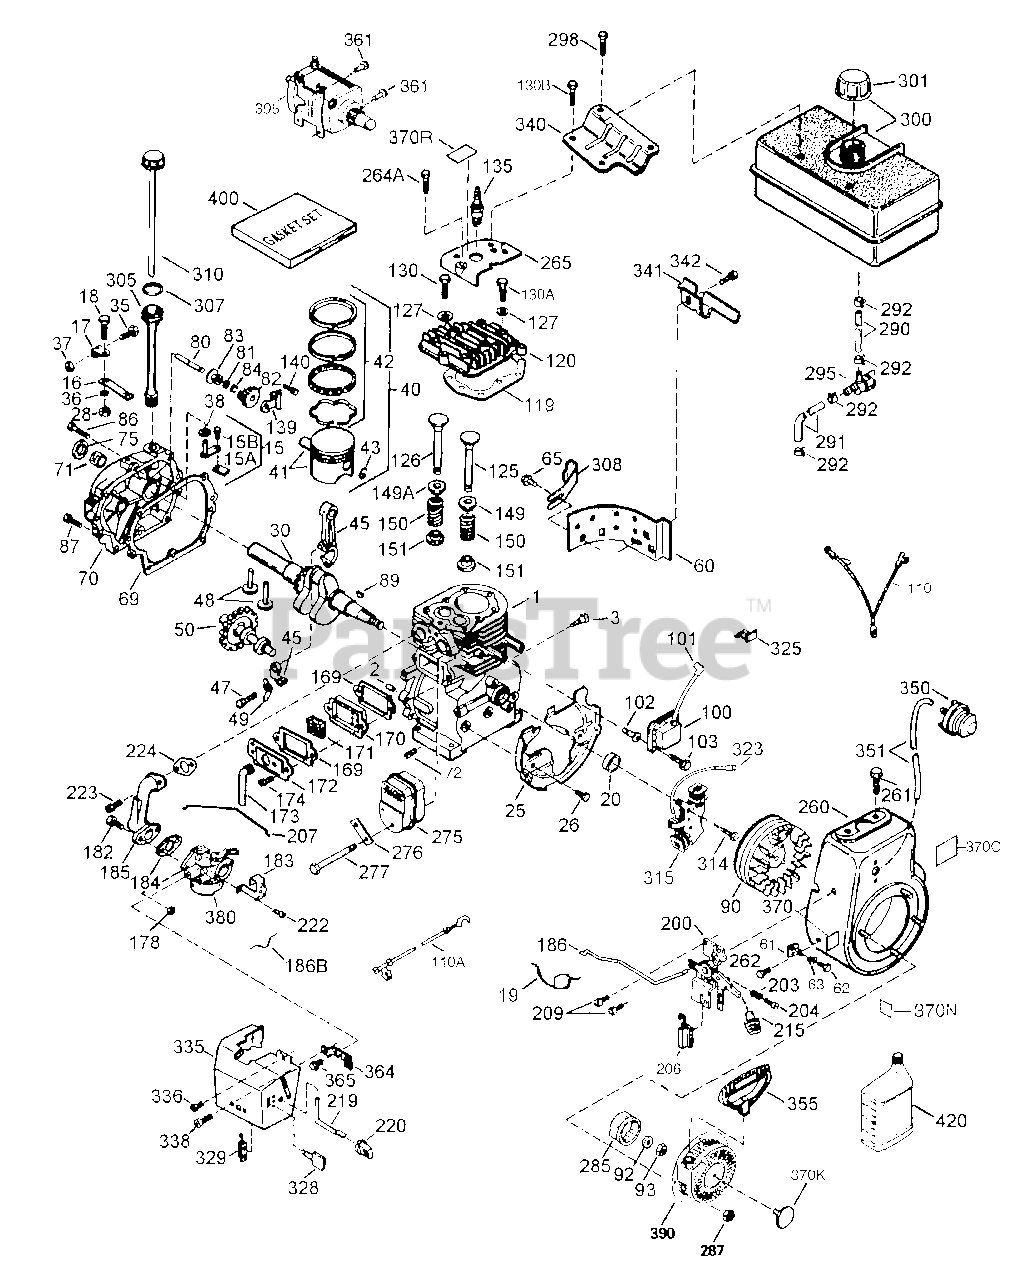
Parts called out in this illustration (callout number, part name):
1	Cylinder Asm (Incl. Ref. #2, 20, &72)
2	Dowel Pin
3	Screw
15	Governor (Incl. Ref. #15A &15B)
15A	Governor Yoke
15B	Screw
16	Governor Lever
17	Governor Lever Clamp
18	Screw
19	Spring-SpeedControl
20	Oil Seal
25	Blower Housing Baffle
26	Screw
28	Lock Nut
30	Crankshaft
35	Screw
36	Lock Washer
37	Lock Nut
38	Retaining Ring
40	Piston, Pin & Ring Set(Std.)
40	Piston, Pin & Ring Set (.010" OS)
41	Piston & Pin Asm(Std.)(Incl. Ref. #43)
41	Piston & Pin Asm(.010" OS)(Incl. Ref. #43)
42	Ring Set (Std.)
42	Ring Set (.010" OS)
43	Piston Pin RetainingRing
45	Connecting Rod Asm (Incl. Ref. #47, & 49)
47	Connecting Rod Bolt
48	Valve Lifter
49	Oil Dipper
50	Camshaft (MCR)
60	Blower HousingExtension
61	Grommet MountingBracket
62	Screw
63	Grommet
65	Screw
69	Cylinder Cover Gasket
70	Cylinder Cover (Incl. Ref. #71, 75, &80)
71	Crankshaft Bushing
72	Oil Drain Plug
75	Oil Seal
80	Governor shaft
81	Washer
82	Governor Gear Asm (Incl. Ref. #81)
83	Governor Spool
84	Retaining Ring
86	Screw
87	Screw
89	Flywheel Key
90	Flywheel (W/RingGear)
92	Lock Washer
93	Flywheel Nut
100	Solid State Ignition
101	Spark Plug Cover
102	Solid State MountingStud
103	Screw, Torx T-15
110	Ground Wire
110A	Ground Wire
119	Cylinder Head Gasket
120	Cylinder Head
125	Exhaust Valve (Std.)(Incl. Ref. #151)
125	Exhaust valve (1/32"OS)(Incl. Ref. #151)
126	Intake Valve (Std.)(Incl. Ref. #151)
126	Intake Valve (1/32" OS)(Incl. Ref. #151)
127	Washer
130	Screw
130A	Screw
130B	Screw
135	Resistor Spark Plug (RJ19LM)
139	Governor Gear Bracket
140	Screw
149	Valve Spring Cap
149A	Valve Spring Cap
150	Valve Spring
151	Valve Spring Keeper
169	Valve Cover Gasket
170	Breather Body
171	Breather Element
172	Valve Cover
173	Breather Tube
174	Screw
178	Nut & Lock Washer
182	Screw
183	Choke Bracket
184	Carburetor To IntakePipe Gasket
185	Intake Pipe
186	Governor Link
186B	Spring-Choke
200	Control Bracket (Incl.Ref.#19, 203, 204 & 206)
203	Compression Spring
204	Screw
206	Terminal
207	Throttle Link
209	Screw
215	Control Knob
219	Choke rod
220	Choke Knob
222	Screw
223	Screw, Torx T-30
224	Intake Pipe Gasket
260	Blower Housing
261	Screw
262	Screw, Torx T-40
264A	Screw
265	Cylinder Head Cover
275	Muffler
276	Locking Plate
277	Screw
285	Starter Cup
287	Nut & Lock Washer
290	Fuel Line
291	Fuel Line
292	Fuel Line Clamp
295	Fuel shut-Off Valve
298	Screw
300	Fuel Tank (Incl. Ref. #292 & 301)
301	Fuel Cap
305	Oil fill Tube
307	"O" Ring
308	Fill Tube Clip
310	Dipstick
314	Screw
315	Alternator Coil (18Watt)(Incl. Ref. #323)
323	Terminal
325	Wire Clip
328	Ignition Keys
329	Terminal
335	Carburetor Cover
336	Screw
338	Screw
340	Fuel Tank Bracket
341	Fuel Tank Bracket
342	Screw
350	Primer Bulb
351	Primer Line
355	Starter Handle
361	Screw, Torx T-30
364	Carburetor CoverBracket
365	Screw
370	Identification Decal
370C	Primer Decal
370K	Starter-Decal
370N	Bilingual Decal
370R	Warning Decal
380	Carburetor (Incl. Ref.#184)
390	Rewind Starter (Note: This engine could have been built with 590749 starter.)
395	Electric Starter Motor, 120 Volt (Optional)
400	Gasket Set
420	SAE 5W30 4-Cyc.Eng. Oil
